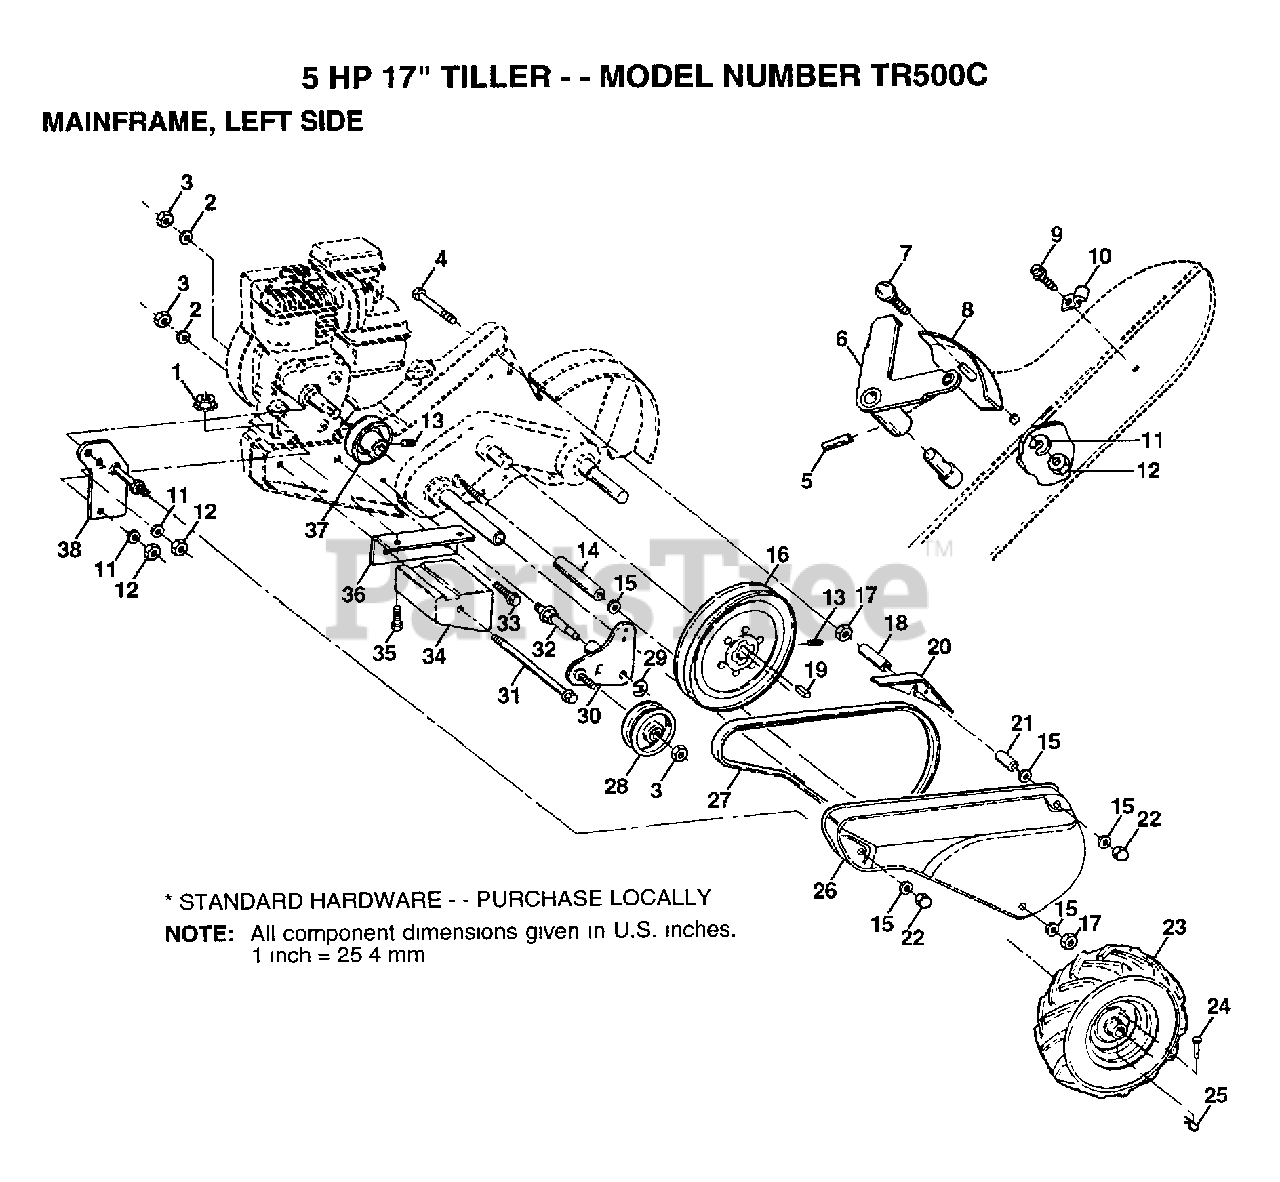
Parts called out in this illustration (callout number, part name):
2	LOCKWASHER
3	NUT.HEX.3/8-16UNC
4	BOLT TI
6	LEVER ASM CRT
7	BOLT
8	PANEL TI
10	CONDIUT CLIP T
11	LOCKWASHER
13	SET SCREW
14	SPACER
15	WASHER
16	"SHEAVE 10"" CRT"
17	NUT.HEX.5/16-18
18	SPACER CRT
19	KEY T
20	GUARD CRT
21	SPLIT SPACER
22	NUT TI
23	TIRE.CHV.13X5.0-6
24	RIVET.DRILL.1.75
25	RETAINER M
26	"GUARD, BELT"
27	BELT-V
28	PULLEY-IDLER TI
29	KLIP RING
31	BOLT CRT
32	SHIFT ARM CRT
33	BOLT
34	COUNTERWEIGHT CRT
35	BOLT.HEX.5/16-1.5
36	BRACKET LH CRT
37	ENGINE SHEAVE
38	BELT GUARD BRKT
